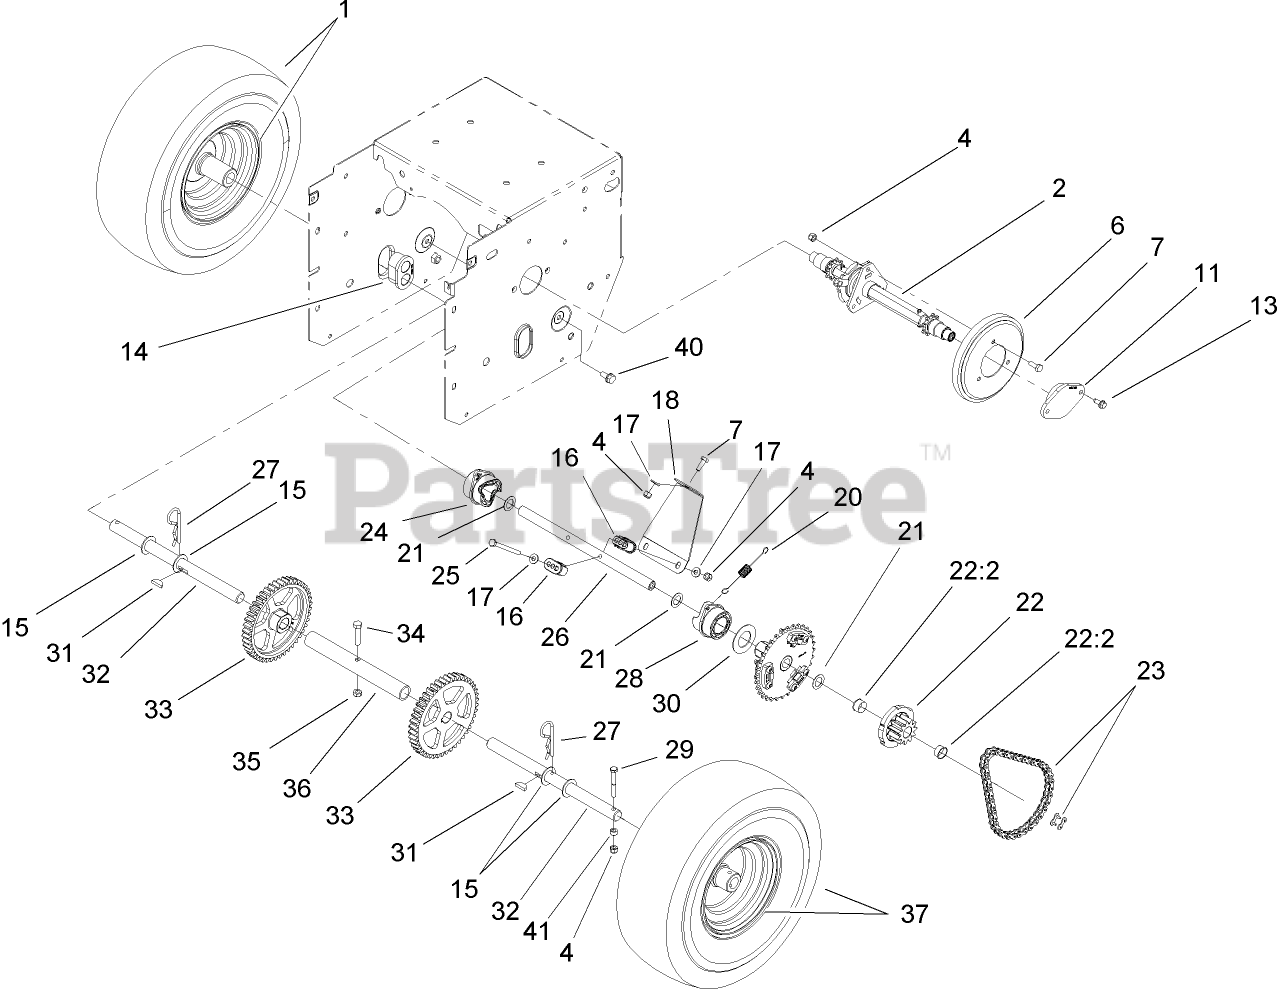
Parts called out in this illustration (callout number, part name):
1	Loose Parts Package
1	RIM-TIRE
4	NUT-LOCK, NI
7	SCREW-HH
11	SEE BULLETIN SNOW PRODUCT#78
13	SCREW-HWH
14	BEARING-AXLE
15	WASHER-THRUST
16	GUIDE-COLLAR
17	WASHER-FLAT
18	BRACE-COLLAR, SHIFT
20	SPRING-EXTENSION
21	WASHER-FLAT
22	11T GEAR ASM
22:2	BUSHING-FLANGE
23	CHAIN-ROLLER
23	LINK-CONNECTING
24	COLLAR-SHIFT, RH
25	SCREW-HH
26	SHAFT-INTERMEDIATE
27	PIN-HAIR
28	COLLAR-SHIFT, LH
29	SCREW-HH
30	WASHER-THRUST
31	KEY-WOODRUFF
32	SHAFT-AXLE
33	GEAR-AXLE, 44 TOOTH
34	SCREW-HH
35	NUT-LOCK, NI
36	TUBE-AXLE
37	Loose Parts Package
37	RIM-TIRE
40	SCREW-HWHTF
41	SPACER-BLADE, ROTOR
